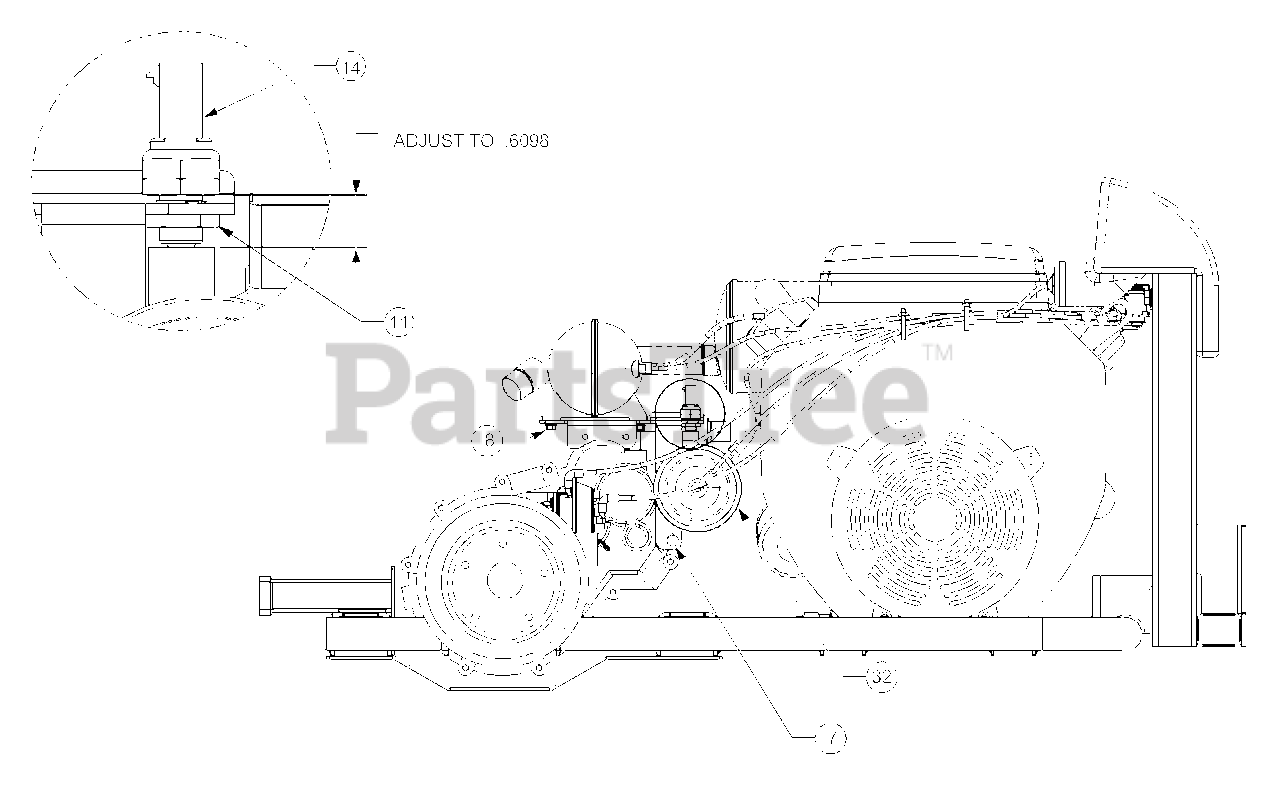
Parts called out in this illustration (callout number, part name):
7	Screw, 5/16-18
8	Screw, 1/4-14
11	Nut, Hex 9/16-18
14	Switch, Neutral
32	Actuator, Vacuum Shift
